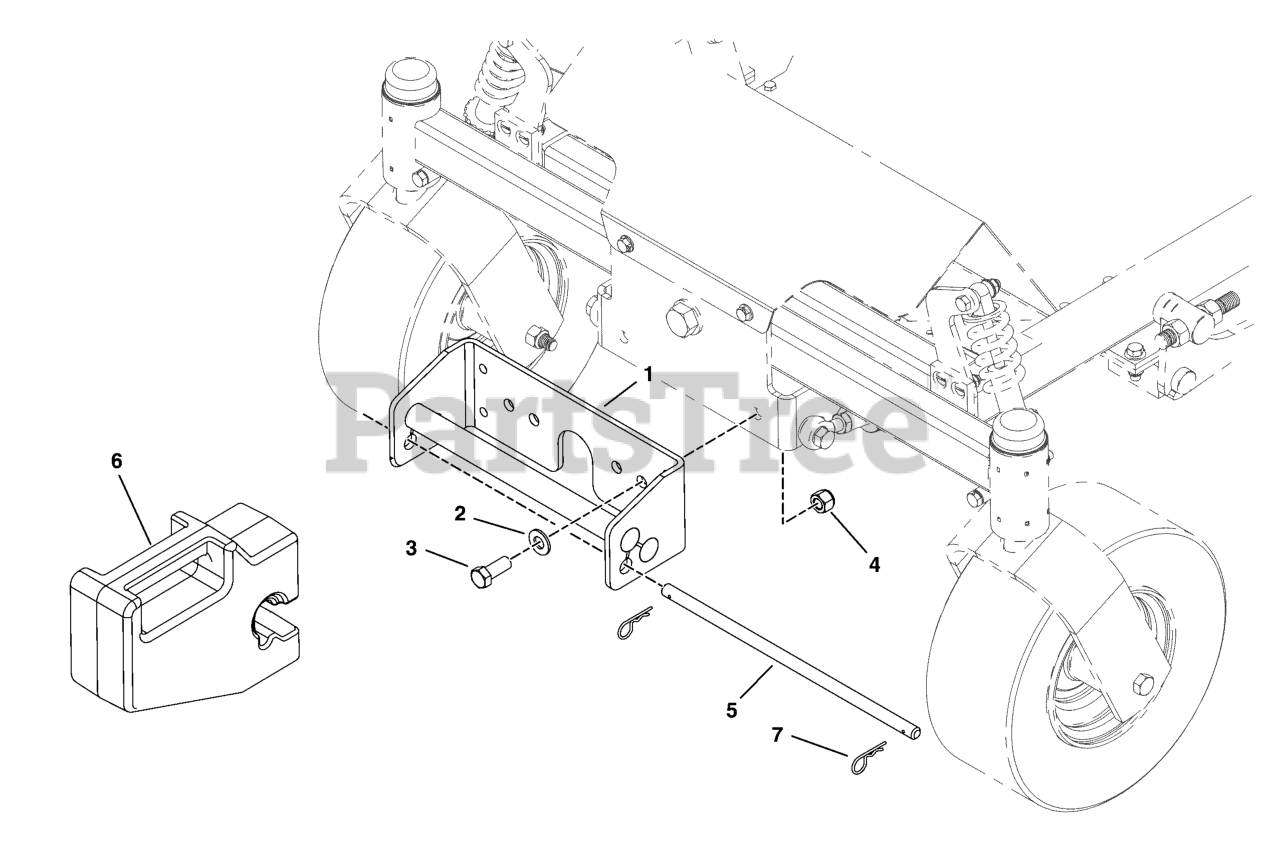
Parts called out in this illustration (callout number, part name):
1	HOLDER ASMY-WEIGHT CONS Z CAT - BLACK
2	WASHER, 1/2 SAE
3	BOLT, 1/2-20 X 1-1/4" GD5 CZ
4	NUT, Hex, Nylon Lock, 1/2-20
5	ROD-.500DIA 13.75LG YELLOW CON
6	WEIGHT-QUICK ATTACH 33LBS PAINTED BLACK
7	3/32 X 1-5/8 HAIR PIN CLIP
